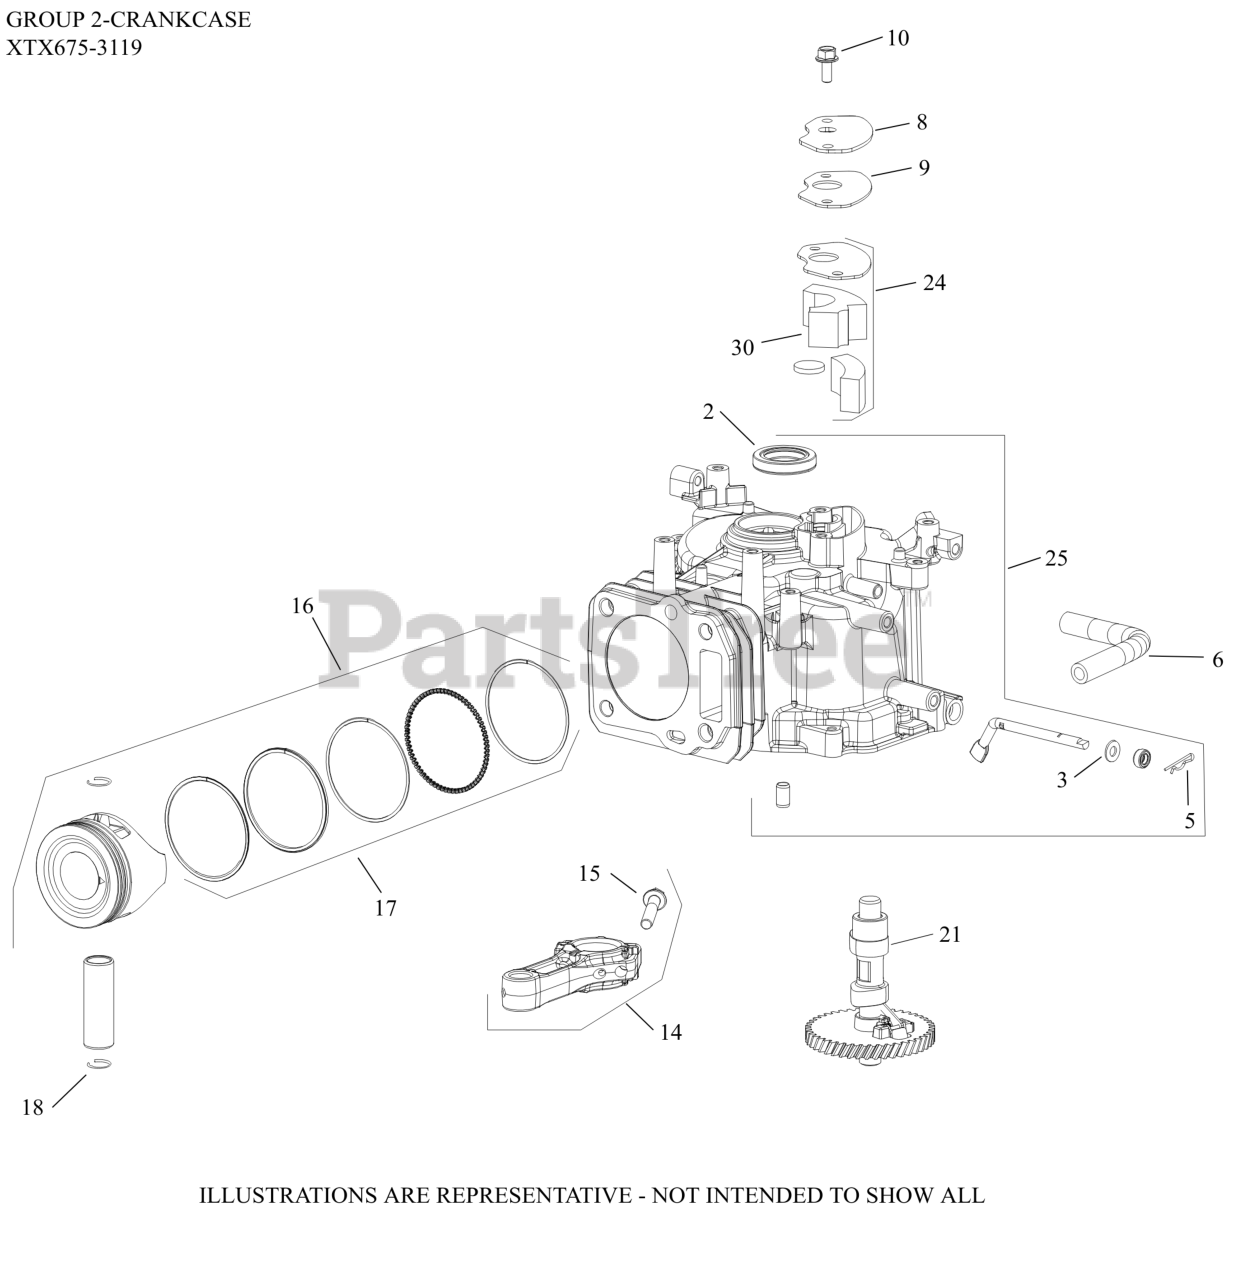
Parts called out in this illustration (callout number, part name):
2	SEAL, CCASE/FLYWHEEL
3	WASHER, FLAT (DIA 13mm O.D.)
5	CLIP, GOVERNOR SHAFT
6	HOSE, BREATHER
8	COVER, BREATHER
9	GASKET, BREATHER COVER
10	SCREW, HEX FLANGE (M6)-USE 25 086 433-S
14	ROD, CONNECTING ASSEMBLY
15	SCREW, HEX FLANGE (M7)
16	PISTON ASSEMBLY (SERVICE)
17	RING SET (SERVICE) (XT149)
18	RETAINER, PISTON PIN
21	CAMSHAFT, ASSEMBLY
24	KIT, BREATHER FILTER
25	KIT, CRANKCASE
30	FILTER, BREATHER MEDIA-USE 14 050 31-S
